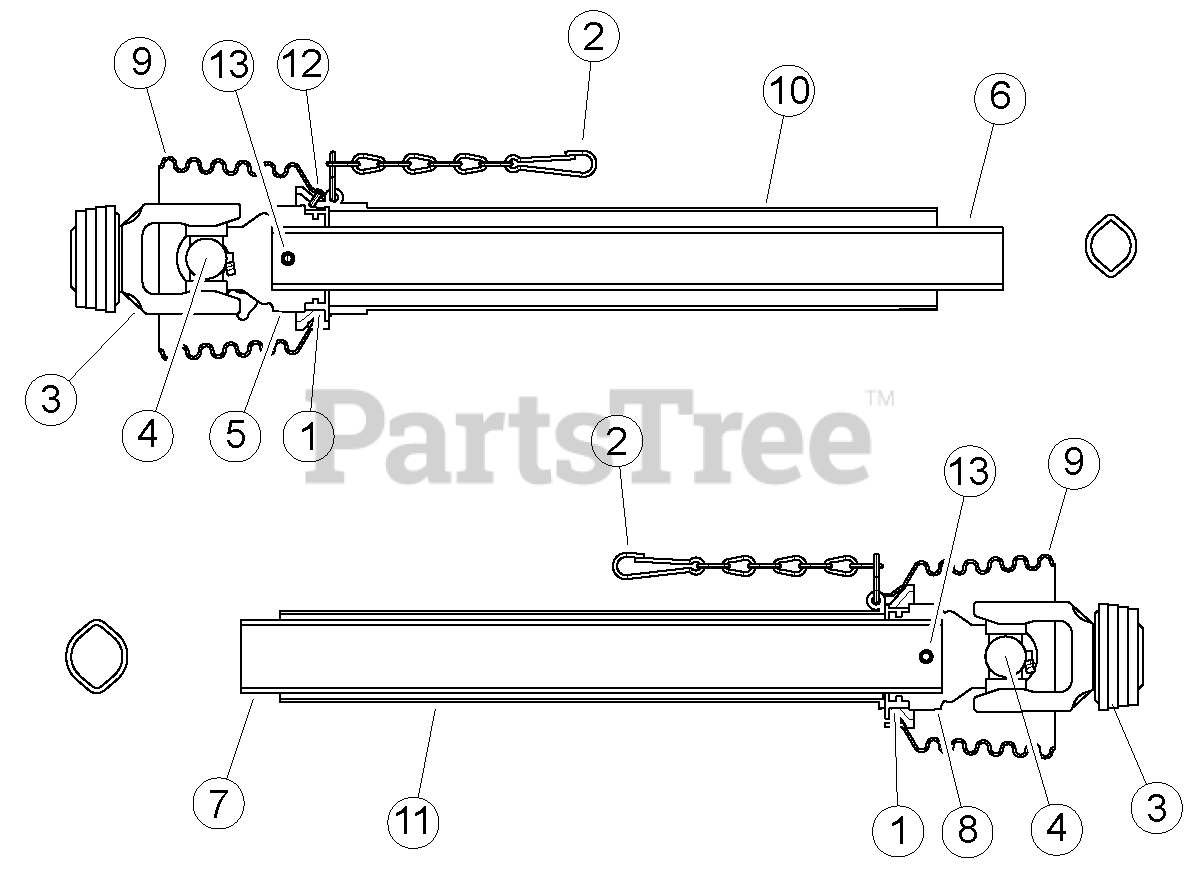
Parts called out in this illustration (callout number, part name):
1	RING, SC15 BEARING
2	CHAIN, SAFETY
3	YOKE, 1-3/8-6 SPLINGE ASGE
4	KIT, CROSS & BEARING
5	YOKE, INBOARD 0V
6	PROFILE, INNER 0V
7	PROFILE, OUTER 1
8	YOKE, INBOARD 1
9	CONE, 4 RIB
10	GUARD, TUBE OUTER
11	GUARD, TUBE INNER
12	SCREW, WS365344
13	PIN, 10 X 65 SPRING
